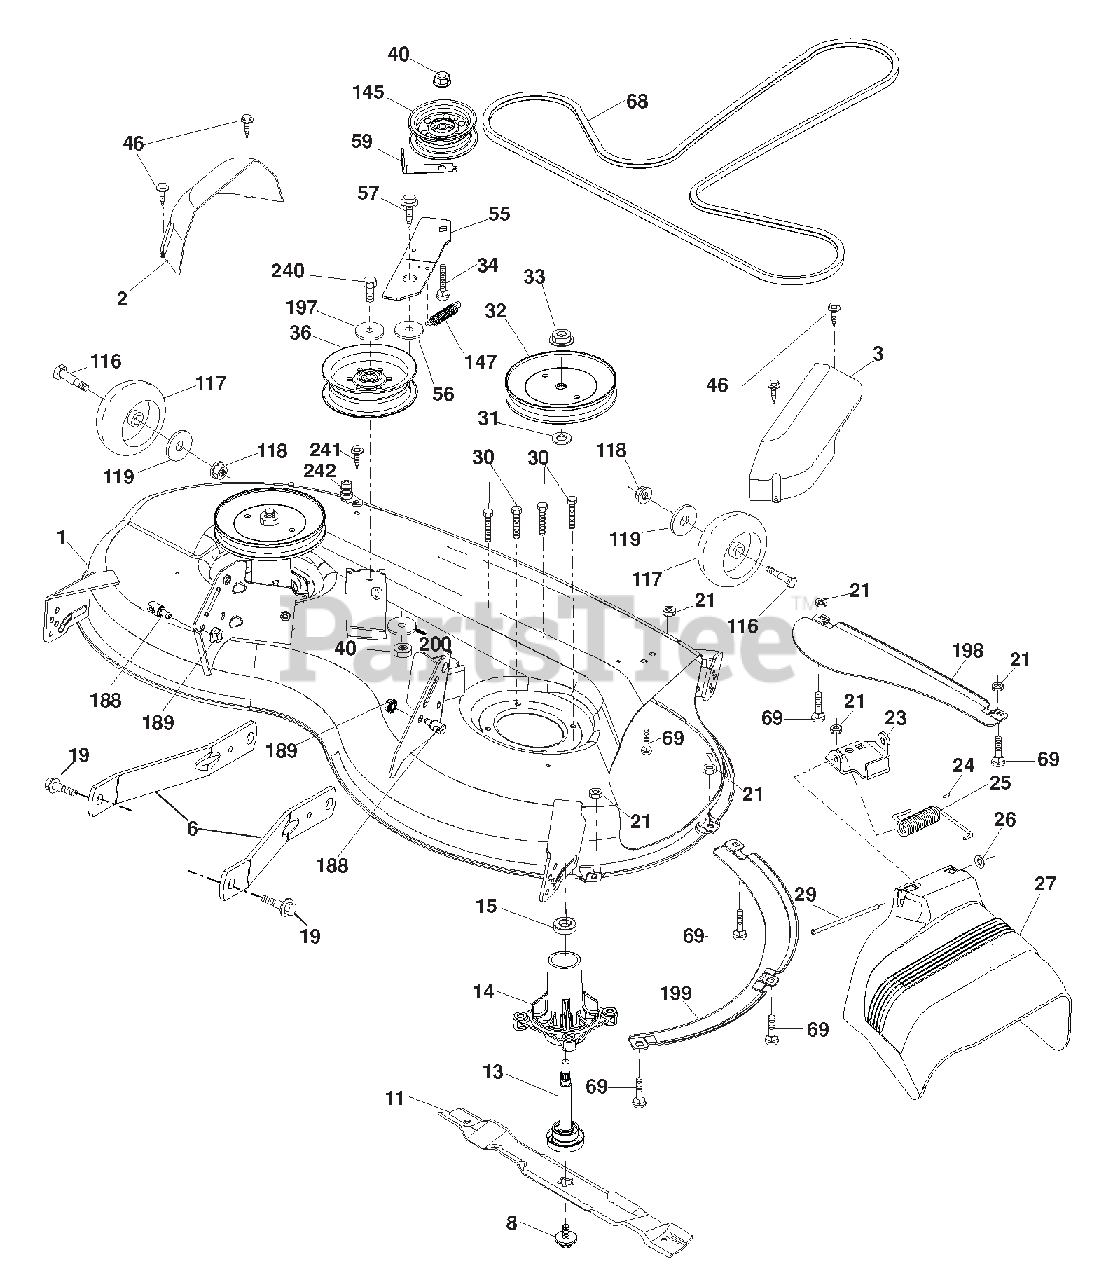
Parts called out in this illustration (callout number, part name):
1	MOWER HOUSING
2	COVER.MANDREL.LH.46"
3	COVER.MANDREL.RH.46"
6	ARM.SUSPENSION.MOWER.REAR.LD
8	BOLT/WASHER ASM.7/16-20.UNF
11	BLADE.MOWER.46"HI LIFT BAGGER
13	SHAFT ASM.MNDRL.N/GREASEABLE38
14	HOUSING.MANDREL.4PT.SERVICE
15	BEARING.BALL.MANDREL
19	BOLT.SHOULDER
21	Nut, Hex, Crownlock 5/16-18
23	BRACKET.DEFLECTOR.38/42"2005
24	CAP.SLEEVE..80X.112.BLK.MOWER
25	SPRING.TORSION.DFL.38/42/46.GR
26	NUT.PUSH.PHOS.& OIL
27	SHIELD.DEFLECTOR.MOWER 46"BLK
29	ROD.HINGE.42/46"
30	SCREW.THD ROLL.DOD PT.HEX
31	WASHER.SPACER.MANDREL
32	PULLEY.MANDREL.5.438 PD.42"
33	NUT.FLANGE.LOCK.TOP
34	BOLT.CARR.SH.3/8-16X1-1/2.GR5
36	PULLEY.IDLER.4.50.RAW
40	Nut, Hex, Flangelock 3/8-16
46	SCREW.THD.ROLL.1/4-20 X 5/8
55	IDLER.ARM
56	SPACER.RETAINER
57	SCREW.3/8-16X1.SMGML.TAP/R.BLK
59	GUARD.TUV.IDLER
68	V-BELT.DRIVE.MWR.MECHANICL.46"
69	BOLT.5/16-18HEX.WHS.HD.LCKSERR
116	BOLD SHLD "A" 2.41 "B" 1.66
117	WHEEL.GAGE.HALF.SPOKED
118	Nut, Hex, Flangelock 3/8-16
119	Washer 3/8 x 7/8 x 14 Ga.
145	PULLEY.IDLER 48"PRIMARY
188	STUD.FASTNER.W/'D'ANTI-ROTATIO
189	Nut, Lock Hex Flange 5/16-18 u
197	Washer 13/32 x 13/16 x 12 Ga.
198	BAFFLE.CENTER.FRONT
199	BAFFLE.FRONT.RH
200	WASHER.13/32 X 1 X 1/2.11GAHRD
240	BOLT.FIN.HEX.3/8-16X 2-1/4 GR5
242	PORT WASHOUT
